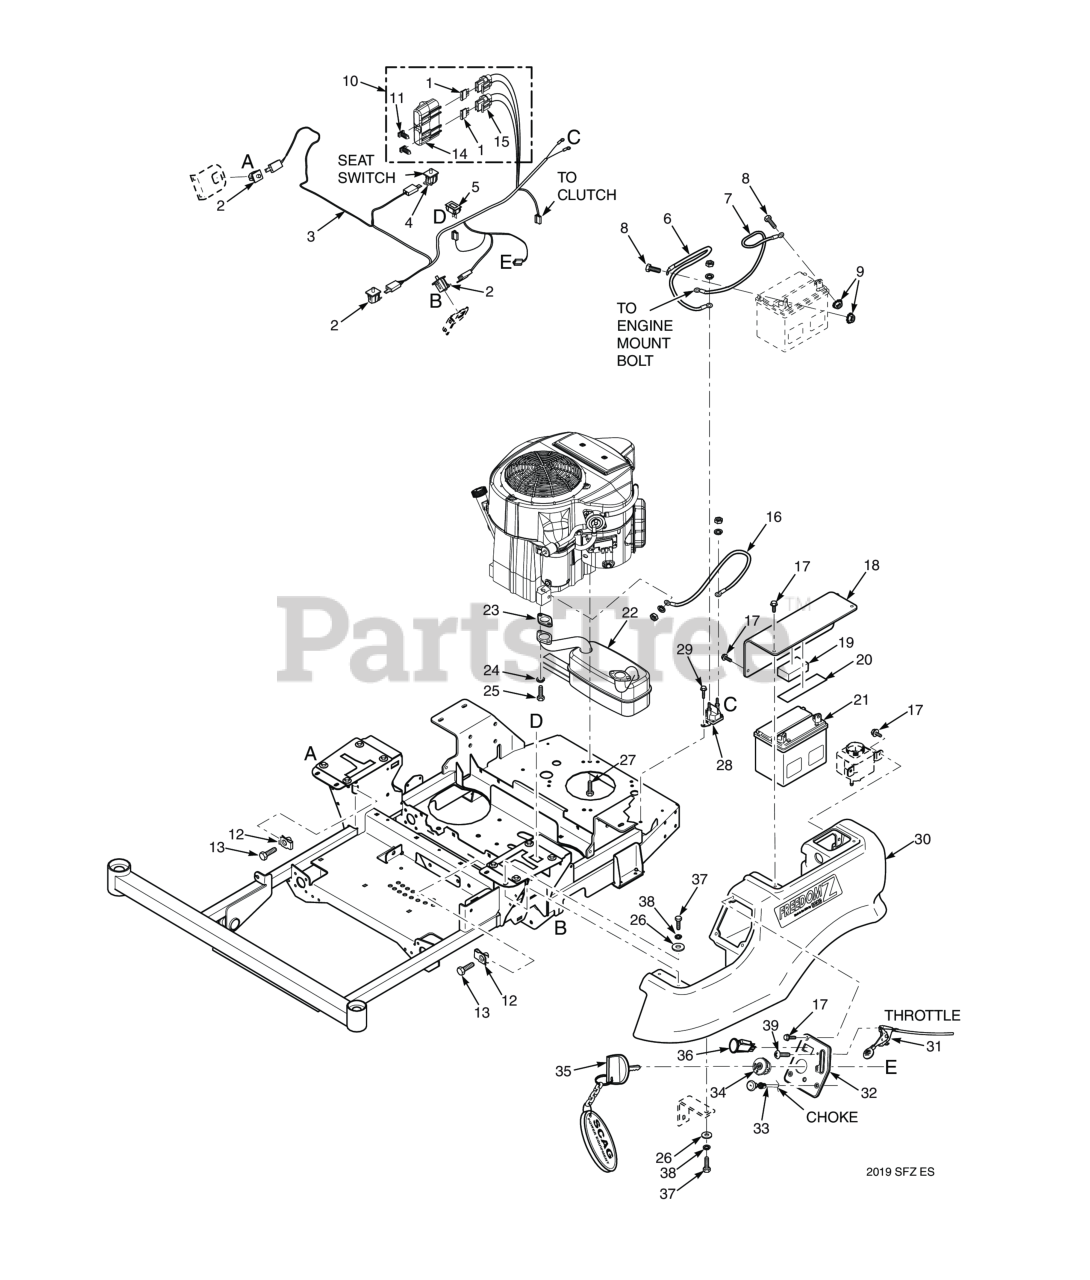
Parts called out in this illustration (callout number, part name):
1	FUSE, 20 AMP BLADE TYPE AUTOMOTIVE
2	Switch, Double Pole - Plunger
3	Wire Harness, Main
4	Switch, Double Pole - Plunger
5	Hourmeter
6	Battery Cable, 25" Red (Kawasaki)
7	Battery Cable, 27" Black (35BV & 37BV-EFI) - Briggs & Stratton
8	Bolt, Hex Head 1/4-20 x .5" Battery, (Not Available Through Scag)
9	Nut, 1/4 - 20 Hex
10	Double Fuse Assy.
11	Clip, Fuse Holder
12	U-Nut, 3/8-16 (short)
13	Bolt, Hex Head 3/8-16 x 1-1/4" with Thread Lock Patch
14	Cover, Sealed Double
15	Fuse Holder Assembly
16	Battery Cable, Red 9" (Briggs & Stratton)
17	CAP SCREW, 1/4-20 X 1/2" SERRATED FLANGE HEX
18	Battery Cover
19	Pad, Battery - Rubber
20	Rubber Pad
21	Battery, 350 CCA (not available through Scag)
22	Muffler, Kohler KT
23	Exhaust Gasket
24	Flatwasher, 5/16-.375 x .875 x .083 (35BV & 37BV-EFI)
25	Bolt, Hex Head 3/8-16 x 1-1/4", Kawasaki FX / FS
26	Lockwasher, 3/8" Spring, Kawasaki FX / FS
27	Bolt, Hex Head Self-Tap 3/8-16 x 1-1/4" (Kohler x3 - 25EFI, Kohler x4 - 29EFI)
28	Solenoid, Sealed (Briggs & Stratton)
29	Screw, 1/4-20 x .375"
30	Tank Console 48
31	Tank, LH - SPZ
32	Throttle Control, Kawasaki
33	INSTR PANEL W/ DECAL, SFZ
34	Choke Control, Kawasaki
35	Ignition Switch
36	Key, Assembly w/Fob
37	Switch, PTO - 10 Amp
38	BOLT, SERRATED FLANGE HEX HEAD 5/16-18 X 3/4"
39	Lockwasher, 5/16 (.317 x .586 x .078) Helical Spring
